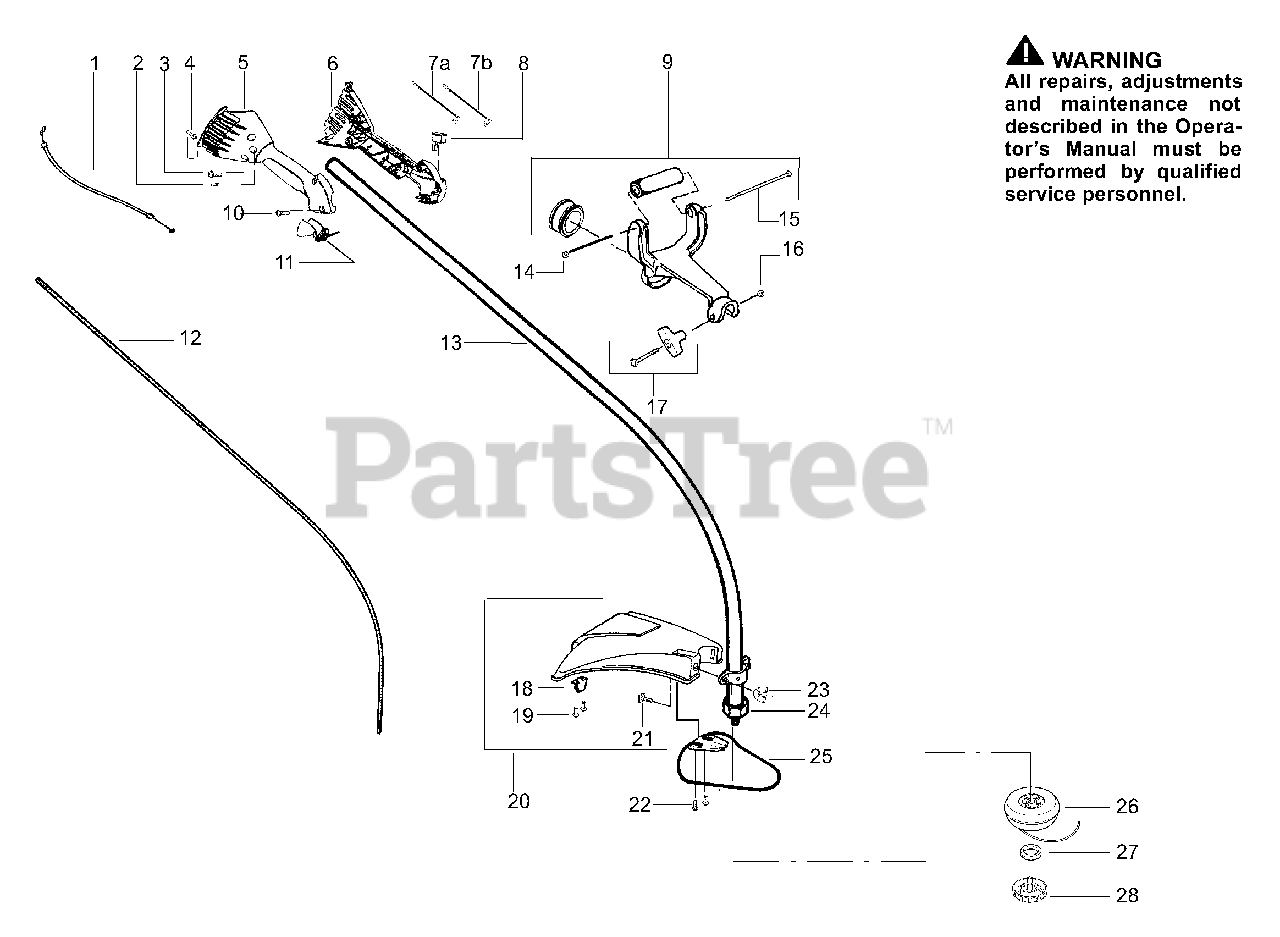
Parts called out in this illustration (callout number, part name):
1	Assy-Throttle cable
2	Screw-alignment
3	Screw-10-24
4	Screw-handle/fan hsg.
5	Throttle Hsg.-Right
6	Kit-Left Throttle Hsg.
7A	Assy-Front wire
7B	Assy-Front Wire (upper)
8	Kit-Switch
9	Assy-Antivibe Handle
11	Trigger-Throttle
12	Shaft-Flex
13	Assy-Driveshaft
16	Nut-1/4-20"
17	Assy-"T" Handle
18	Limiter-Line
20	Kit -Shield Ass'y.
22	Screw-Wire Guard
23	Wingnut
25	Assy-Wire Guard
26	Assy-Wound Hub
27	Guide-Line
28	Assy-Cap & Spring
